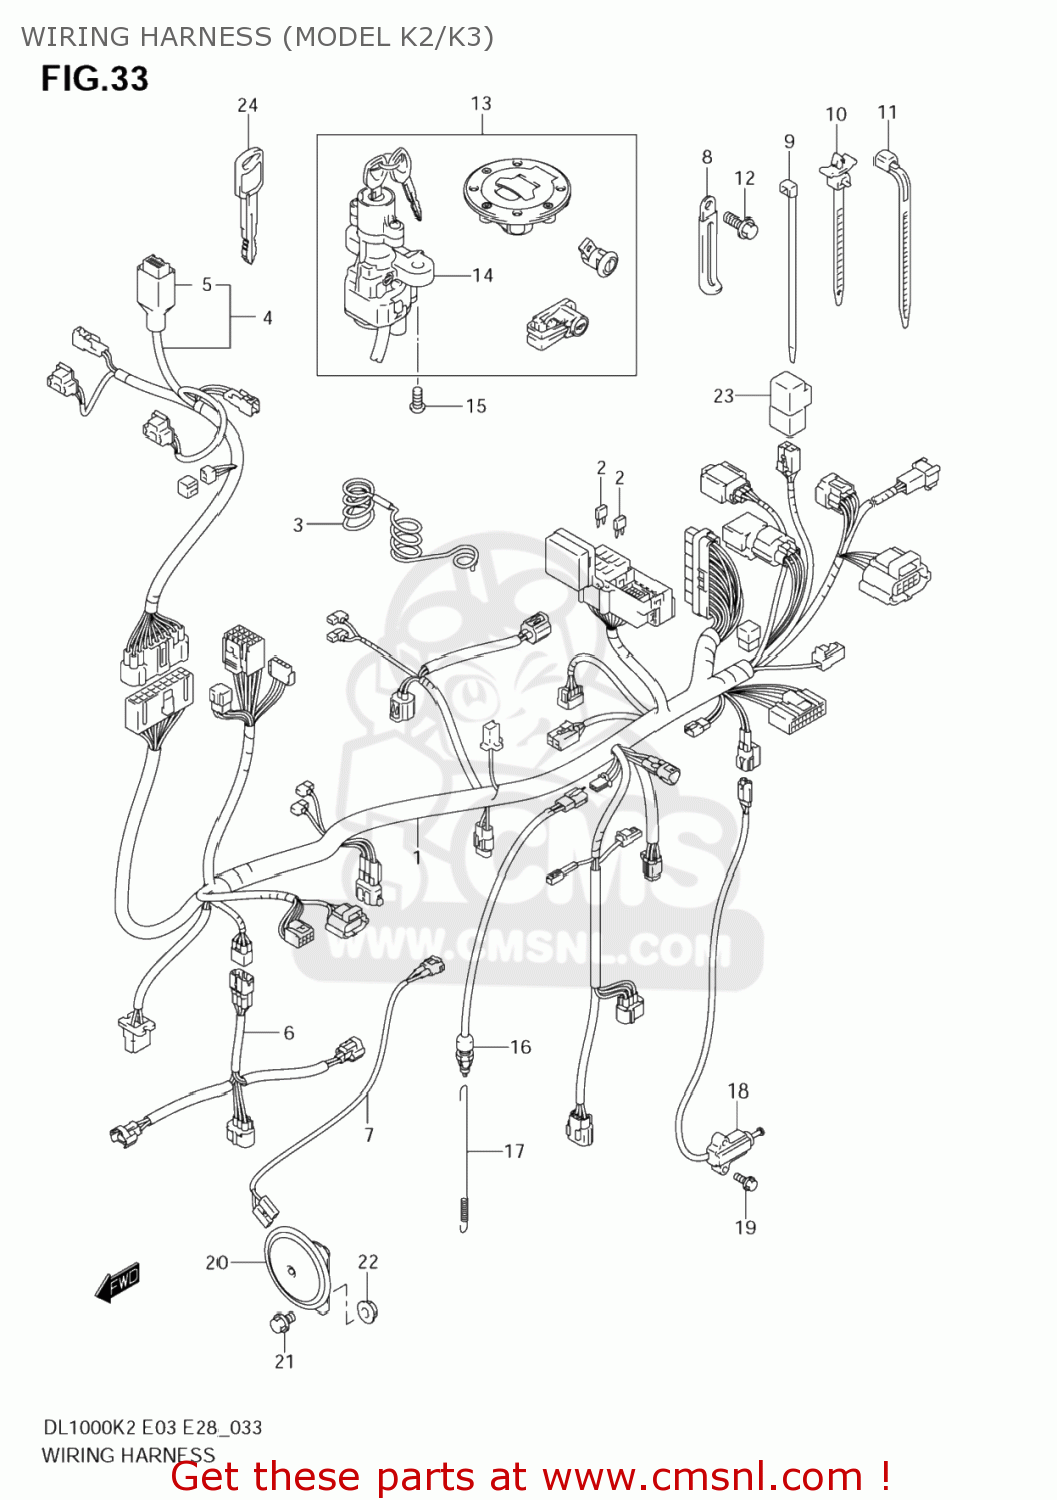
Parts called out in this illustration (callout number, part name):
1	HARNESS, WIRING NO.1
2	FUSE(10A)
3	GUIDE,WIRING H
4	HARNESS,WIRING NO.2
5	COVER,SPEEDOMETER COUPLER
6	WIRE,INJECTOR LEAD
7	WIRE,HORN LEAD
8	CLAMP(L:65)
9	CLAMP(L:145)
10	CLAMP
11	CLAMP(L:125)
12	BOLT
13	LOCK SET
14	LOCK ASSY,STEERING
15	BOLT(8X20)
16	SWITCH ASSY,STOP LAMP
17	SPRING,STOP LAMP SWITCH
18	SWITCH ASSY,SIDE STAND
19	BOLT
20	HORN ASSY
21	BOLT
22	NUT
23	RELAY ASSY
24	KEY,BLANK
